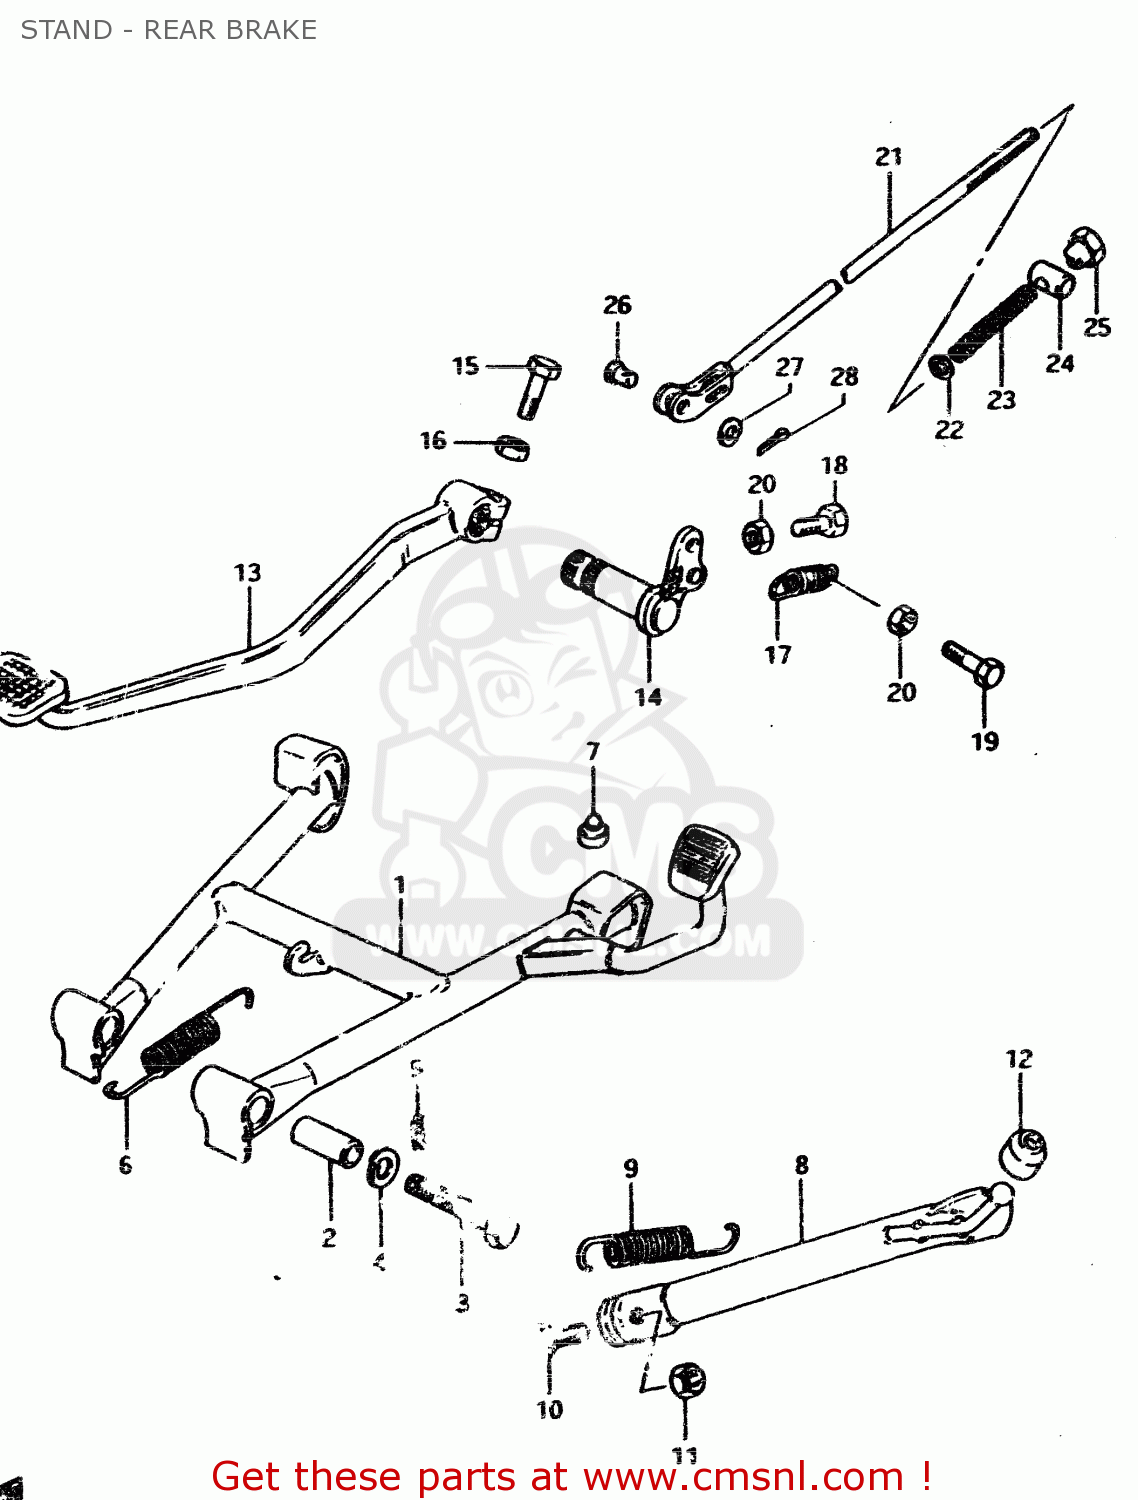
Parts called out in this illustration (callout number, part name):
1	STAND,CENTER
2	SPACER(10X16X38.8)
3	BOLT
4	LOCK WASHER
5	CLIP
6	SPRING
7	CUSHION
8	STAND,SIDE
9	SPRING
10	BOLT(10X30)
11	NUT
12	CUSHION
13	PEDAL,BRAKE
14	ARM,BRAKE PEDAL
15	BOLT
16	LOCK WASHER
17	SPRING
18	BOLT
19	BOLT
20	NUT
21	ROD ASSY,RR BRAKE
22	WASHER
23	SPRING
24	PIN
25	NUT (6MM)
26	PIN(L:13.5)
27	WASHER
28	PIN 20X20
